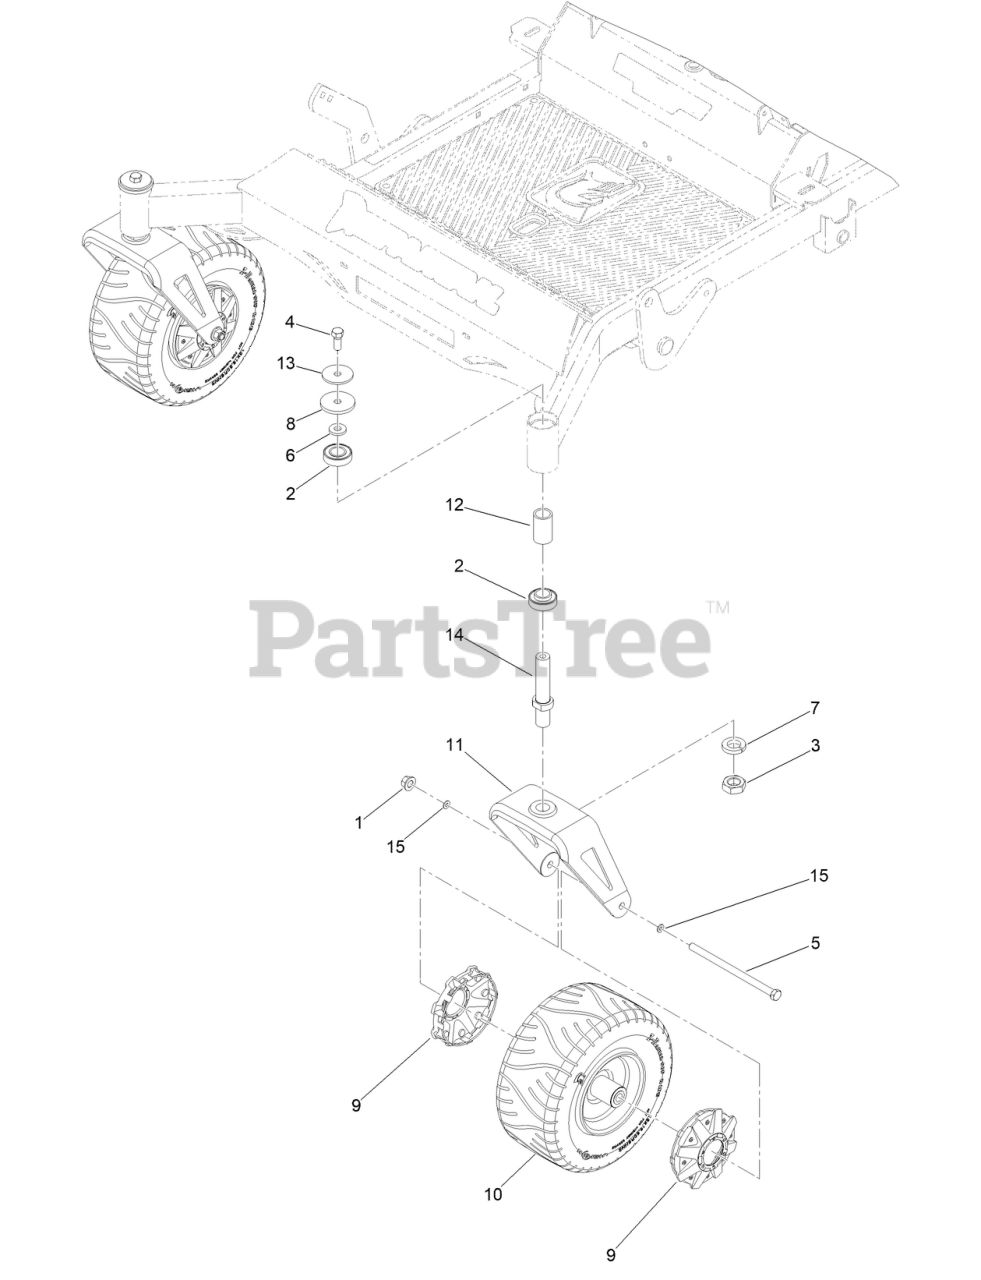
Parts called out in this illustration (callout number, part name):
1	NUT-LOCK
2	BEARING-BALL
4	1/2-20 X 1-1/4 HEX FLANGE BOLT GR 8 YZ
5	1/2-13 X 8-1/2 HEX C/S GR 5 ZINC YELLOW
6	1/2 FENDER WASHER 1-1/4IN OD ZINC
7	1IN L/W MED SPLIT ZC
8	FT HUB PLASTIC WASHER
9	MWR FT WHEEL HUB CAP
10	SPARTAN RADIAL FT TIRE AND WHEEL ASSM
11	RT AND SRT CASTER WHEEL FORK
12	CASTER FORK SHAFT BEARING SPACER
13	MWR CASTER SHAFT WASHER
14	MWR CASTER SHAFT
15	WASHER-FLAT
